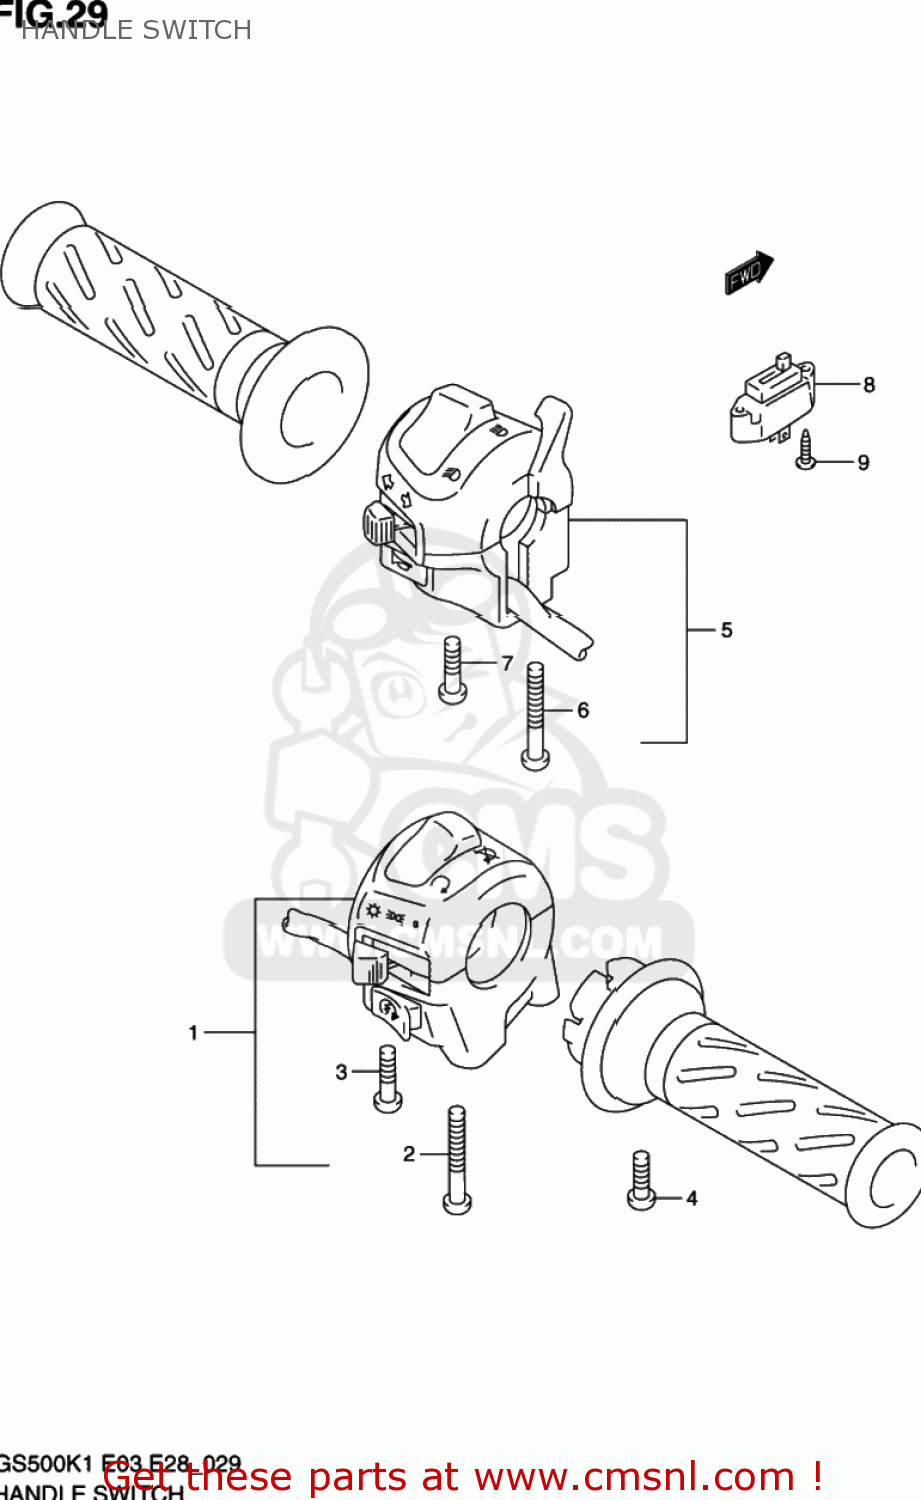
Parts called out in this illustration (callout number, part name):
1	SWITCH ASSY,HANDLE,R
2	SCREW
3	SCREW
4	SCREW
5	SWITCH ASSY,HANDLE,L
6	SCREW, 5X45
7	SCREW(5X25)
8	SWITCH ASSY,CLUTCH
9	SCREW
